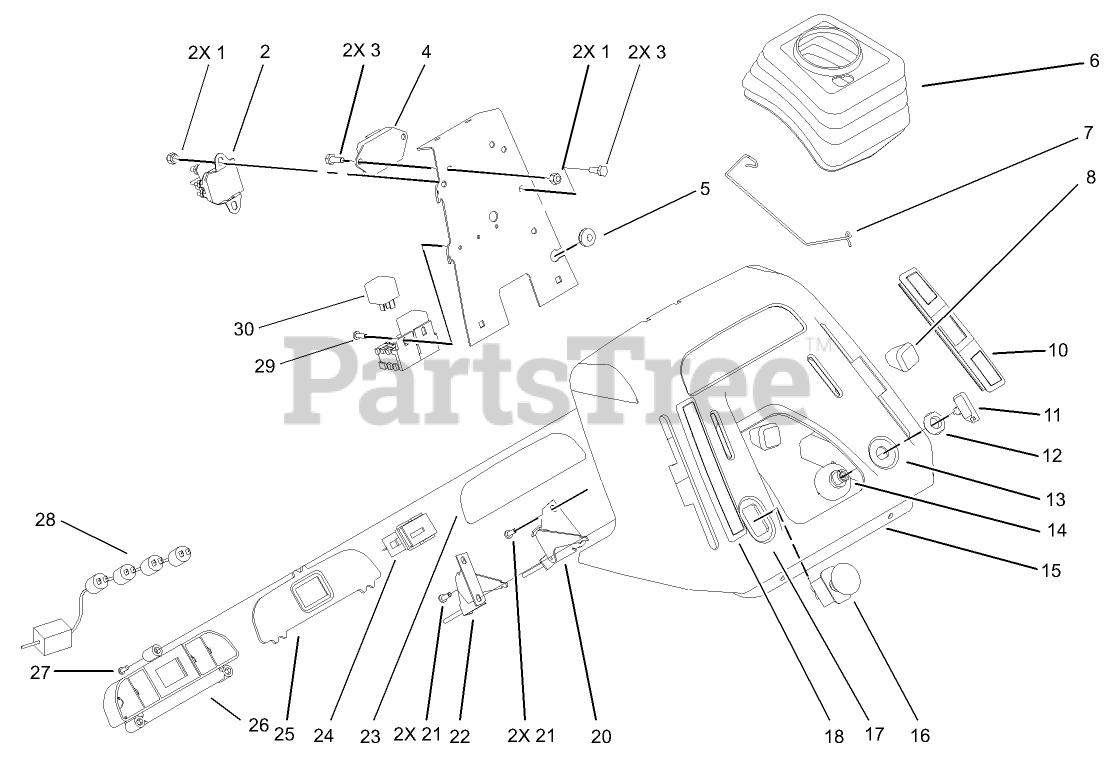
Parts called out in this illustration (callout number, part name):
1	NUT-LOCK, NI
2	SOLENOID-STARTER
3	SCREW-HH
4	MODULE-CLUTCH
5	GROMMET-RUBBER
6	BOOT-STEERING
7	CLIP-BOOT
10	COVER-SLOT, RH
11	KEY-IGNITION
13	DECAL-THROTTLE, IGNITION
14	SWITCH-IGNITION
16	SWITCH-PTO,ON-ON-NONE
17	DECAL-PTO / CHOKE
18	COVER-SLOT, LH
20	CONTROL-THROTTLE
22	CONTROL-CHOKE
23	DECAL-LENS, DASH
24	HOURMETER
25	LENS-DASH
26	HOUSING-LIGHT, INDICATOR
27	SCREW
28	HARNESS-LAMP
29	SCREW-PPHTF
30	RELAY
